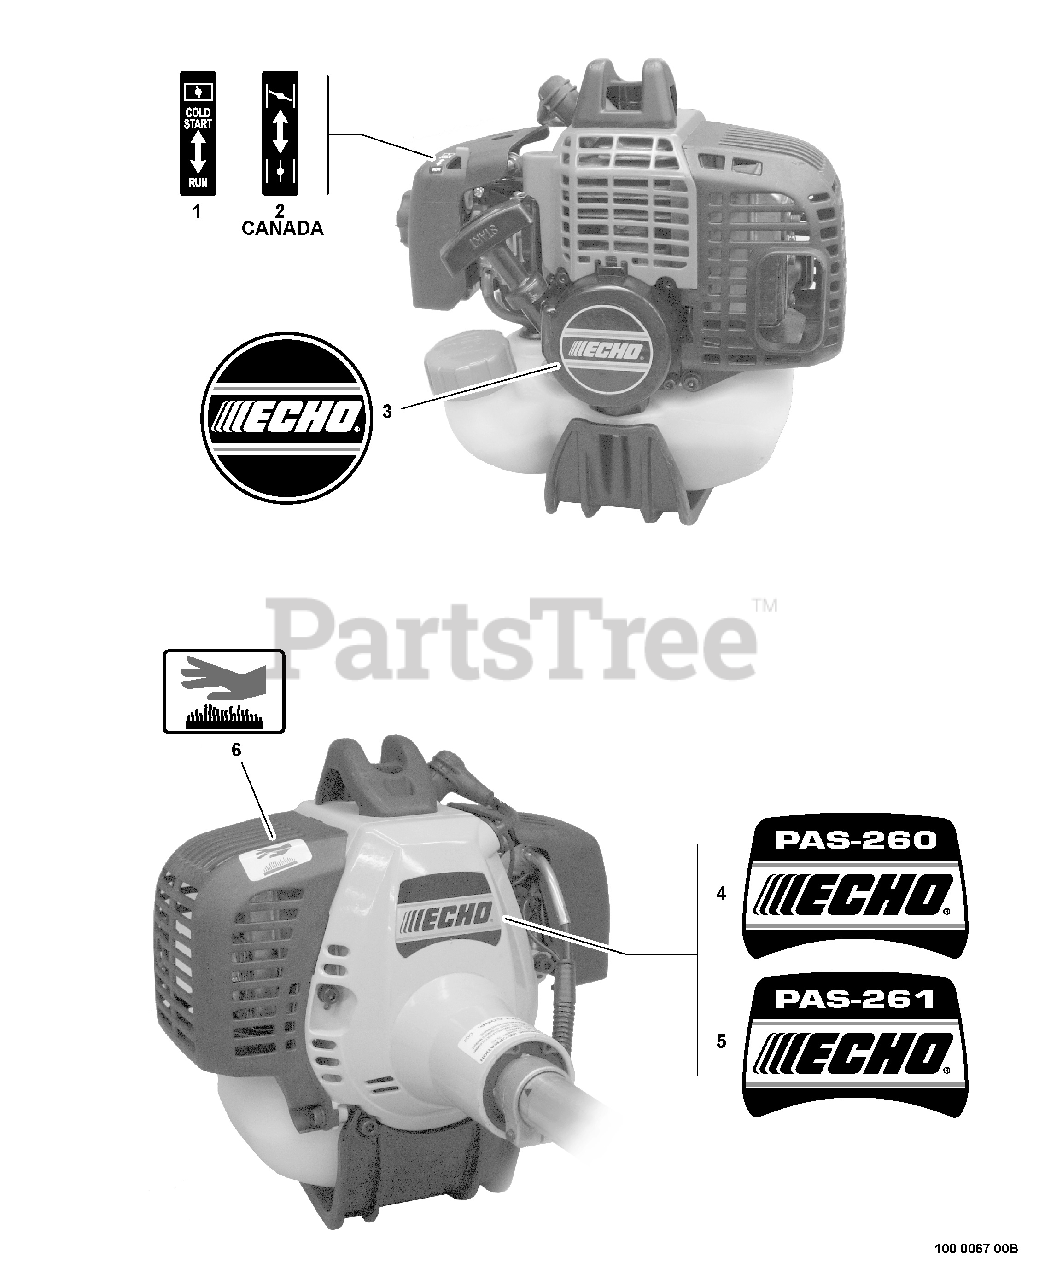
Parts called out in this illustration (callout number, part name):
1	LABEL - CHOKE
2	LABEL - CHOKE
3	LABEL - ECHO
4	LABEL - MODEL PAS-260
5	LABEL - MODEL PAS-261
6	LABEL - HOT SURFACE
